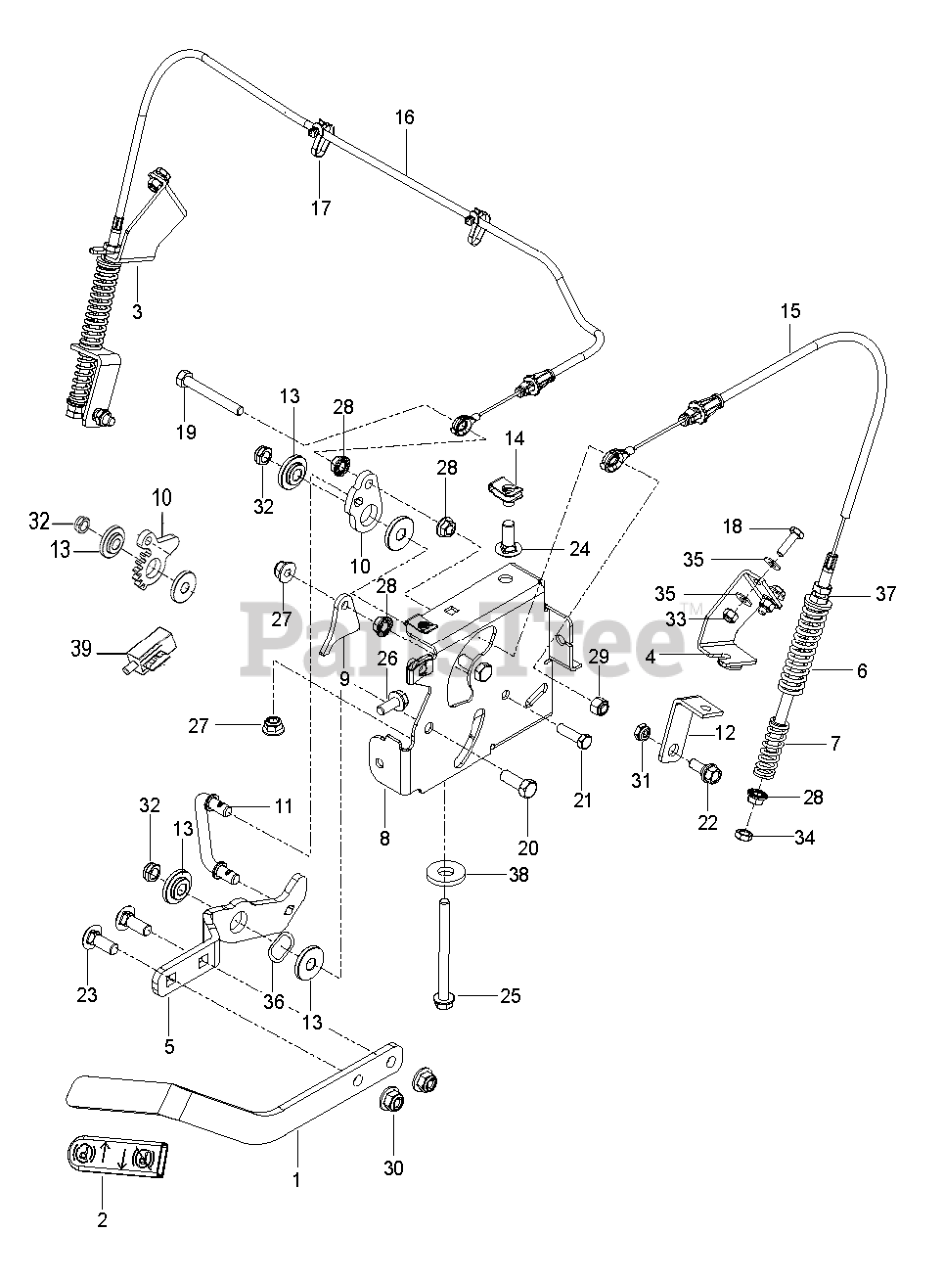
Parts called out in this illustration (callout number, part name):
1	ARM, BRAKE
2	GRIP, PARK BRAKE
3	BRKT, BRAKE RT, BLK
3	BRACKET BRAKE, RT BLACK MS-431
4	BRKT, BRAKE LT, BLK
5	LEVER.PNT.BRAKE.E-DIP
5	GEAR.INPUT.PARKING.BRAKE.MZ
6	SPRING, RETURN
7	SPRING, ENGAGEMENT
8	MOUNT.PNT.BRAKE.MZ.EDIP
8	MOUNT.BRAKET.PNT.BLACK.MS431
9	ACTUATOR, SWITCH
10	BELLCRANK, BRAKE
10	GEAR OUTPUT;PARKING BRAKE;STAN
11	LINKAGE, BRAKE
12	BRKT, BRAKE, BLK
13	BUSHING, BRAKE
14	U-CLIP 5/16-18 NUT RETAINER
15	CABLE.ASSY.BRAKE.CABLE.SHORT
15	CABLE, BRAKE, SHORT
16	CABLE.ASSY.BRAKE.CABLE.LONG
17	TIE WRAP, 8-3/8", W/CLIP
18	HCS 1/4-20X7/8 GR5
19	HCS 5/16-18 X 2 1/2 TPBLT
20	HCS 3/8-16X1.GRD.5.ZD
21	HCS 5/16C X 1
22	BOLT, SHOULDER
23	RHSNB 3/8C X 1
24	BOLT 5/16C X 3/4" CARRIAGE
25	HHFS 5/16-18 X 3 3/4
26	HHFS 5/16-18 X 1.25 TPBLT GD 5
26	HHFS 5/16-18 X 3/4
27	5/16-18 NYLOC FLANGE NUT
28	NUT 5/16C WHIZ
29	NUT 5/16 NYLOC
30	NUT 3/8-16 HEX FLG NYLOC ZD
31	5/16-18 THIN PROF NY
32	NUT HEX 3/8-16 NYLON, THIN
33	NUT.1/4-20.HEX.NYLOC.ZD
34	NUT 5/16C HEX
34	NUT 5/16-18 HEX JAM ZD
35	WASHER 1/4 SAE
36	WASHER, .825 X 1.087, WAVE
37	WASHER 3/8 SAE FLAT
37	WASH USS FLAT 1/2
38	WASHER.9/16 X 1 3/8 X 12 GA.
39	WASH USS FLAT 1/2
